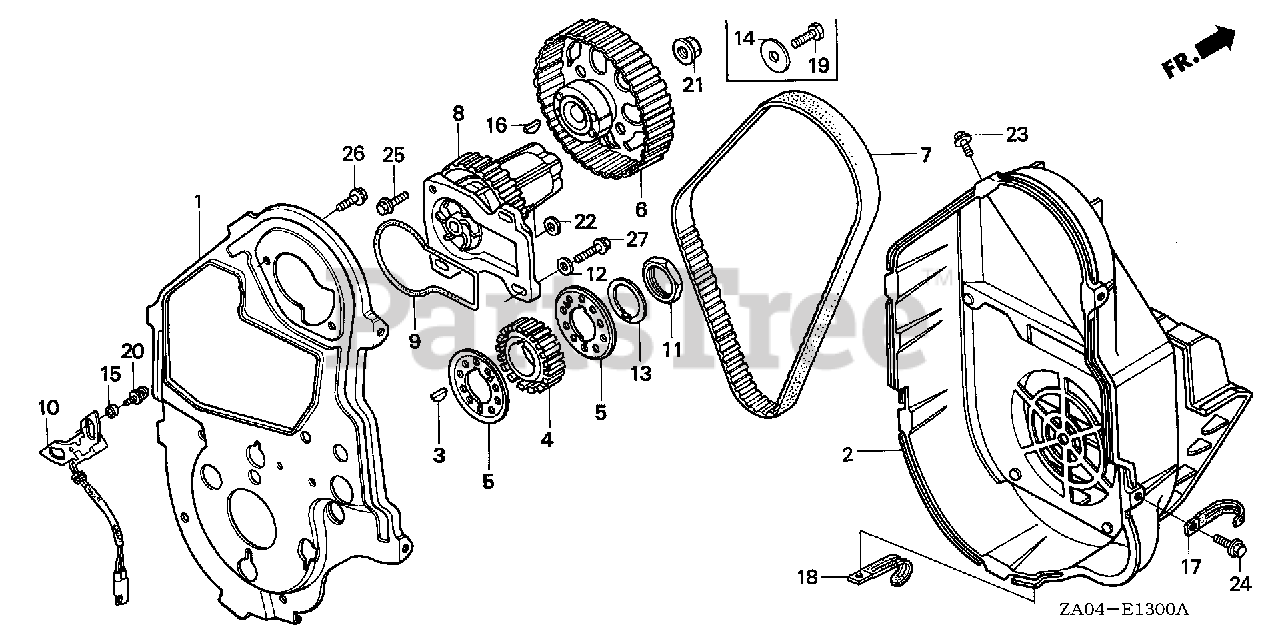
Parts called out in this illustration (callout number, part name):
1	COVER B, TIMING BELT (NOT AVAILABLE)
2	COVER A, TIMING BELT
3	KEY, SPECIAL WOODRUFF (25X18)
4	PULLEY, TIMING
5	FLANGE, TIMING PULLEY
6	CAMSHAFT
6	PULLEY, CAMSHAFT
7	BELT, TIMING
8	WATER PUMP
9	O-RING, WATER PUMP
10	COIL ASSY., PULSER (NOT AVAILABLE)
11	NUT, LOCK (30MM)
12	WASHER, PLAIN (6.5X15)
13	WASHER, LOCK (30MM)
14	WASHER, WHEEL (6MM)
15	PIN, DOWEL (7X4.5)
16	KEY, WOODRUFF (16X12)
19	BOLT, HEX. (6X16)
20	SCREW-WASHER (5X12)
22	WASHER, PLAIN (6MM)
23	BOLT, FLANGE (6X10)
24	BOLT, FLANGE (6X12)
25	BOLT, FLANGE (6X22)
26	BOLT, FLANGE (6X12)
27	BOLT, FLANGE (6X22)
